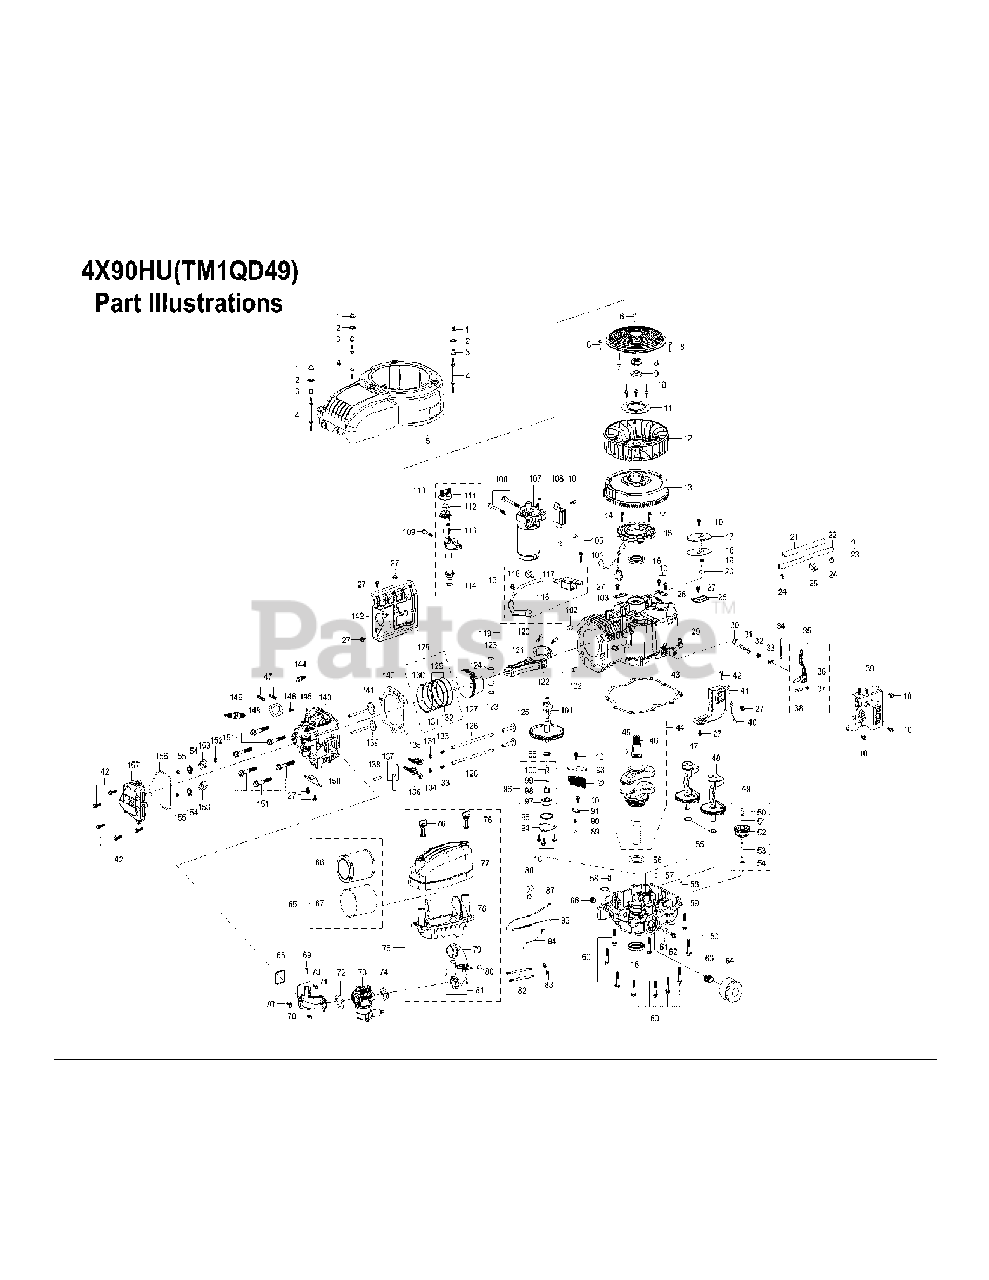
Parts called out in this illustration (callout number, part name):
1	NUT
2	WASHER
3	ENGINE SHROUD SPACER
4	STARTER / SHROUD STUD M6×113
5	SHROUD/AIR SHIELD
6	SCREW 5.5×25
7	DEBRIS SHIELD
8	NUT M20×1.5
9	WASHER 20.5×5×40
10	BOLT M6×14
11	VANE PLATE
12	COOLING FAN
13	FLYWHEEL
14	BOLT M5×25
15	CHARGING COIL
16	OIL SEAL 38×58×8
17	BREATHER COVER
18	GASKET, BREATHER COVER
19	BREATHER VALVE SPRING
20	SECOND AIR VAVLE
21	TUBING PROTECTIVE SIEEVE
22	FUEL HOSE 6.3×12.5×250
24	CLAMP, FUEL HOSE
25	WIRE CLAMP
26	WIRE PLATE II
27	BOLT M6×12
29	CRANKCASE
30	GOVERNOR GEAR SHAFT
31	WASHER 8×0.8×16
32	OIL SEAL 8×14×4
33	COTTER PIN
34	GOVERNOR SPRING
35	GOVERNOR LEVER
36	GOVERNOR ARM
37	GOVERNOR ARM NUT M6
38	GOVERNOR ARM BOLT
39	GOVERNOR GEAR BRACKET ASSY
40	GROUND CONNECTION
41	SHROUD/RIGHT
42	BOLT M6×25
43	GASKET, CRANKCASE COVER
44	CRANKSHAFT ASSEMBLY
45	WOODRUFF KEY
46	CRANKSHAFT
47	BALANCE SHAFT/L
48	BALANCE SHAFT/R
49	GOVERNOR GEAR ASSEMBLY
50	GOVERNOR SLIDE CAP
51	GOVERNOR SHAFT STOP RING
52	GOVERNOR GEAR
53	GOVERNOR SHAFT
54	GOVERNOR GEAR WASHER
55	WASHER 17.2×26×1
56	WASHER 38.3×54×1
57	DOWEL PIN 7×14
58	DOWEL PIN 9×14
59	CRANKCASE COVER
60	BOLT M8×45
61	WASHER 8.3×1.5×17
62	BOLT M8×15
63	FILTER CONNECTOR PIPE
64	OIL FILTER
65	AIR FILTER ELEMENT
66	PAPER FILTER
67	SPONGE FILTER
68	INTAKE PIPE RING
69	SCREW 4.2×20
70	BOLT M6×22
71	INTAKE PIPE
72	CARBURETOR GASKET
73	CARBURETOR
74	AIR FILTER GASKET
75	AIR FILTER ASSEMBLY
76	AIR FILTER COVER SCREW
77	AIR FILTER COVER
78	SILENCER PLATE
79	MANIFOLD
80	RUBBER CAP
81	SCREW 4.2×12
82	STUD M6×92
83	GOVERNOR ARM NUT M6
84	CHOKE LEVER
85	IDLE SPRING
86	DRAIN BOLT
87	THROTTLE LINKAGE
88	VENTING HOUSE
89	STEEL BALL 8.731
90	PRESSURE RELEASE VALVE SPRING
91	PRESSURE RELEASE VALVE COVER
92	FILTER SCREEN
93	FILTER COVER
94	OIL SEPARATER
95	GASKET, CYLINDER HEAD COVER
96	OIL PUMP ASSEMBLY
97	OIL PUMP OUTER SHAFT ROTATOR
98	OIL PUMP INNER SHAFT ROTATOR
99	OIL PUMP PIN
100	OIL PUMP SHAFT
101	CAMSHAFT
102	DOWEL PIN 12×16
103	WIRE PLATE I
104	BOLT M6×28
105	DOWEL PIN 10×12
106	REGULATOR
107	ELECTRIC STARTER
108	BOLT M8×80
109	BOLT M6×45
110	DIPSTICK ASSEMBLY
111	DIPSTICK COVER
112	UPPER O-RING
113	DIPSTICK SEAT
114	LOWER O-RING
115	IGNITION COIL ASSEMBLY
116	VIBRATION PAD
117	WIRE CLAMP
118	IGNITION COIL
119	CONNECTING ROD
120	CONNECTING ROD BOLT
121	CONNECTING ROD CAP
122	CONNECTING ROD
123	CIRCLIP, PISTON PIN
124	PISTON PIN
125	TAPPET
126	PUSH ROD
127	PISTON
128	PISTON RING SET
129	SCRAPER RING, OIL RING
130	1ST PISTON RING
131	2ND PISTON RING
132	LINING RING, OIL RING
133	VALVE CLEARANCE ADJUSTMENT SCREWS COMBINATION
135	ROCKER ARM
136	ROCKER ARM
137	ROCKER ARM CORE SHAFT
138	ROCKER ARM CORE SHAFT BOLT
139	EXHAUST VAVLE
140	GASKET, CYLINDER HEAD
141	INTAKE VAVLE
142	SHROUD/LIFT
143	CYLINDER HEAD
144	HOOK BOLT
145	WASHER 5.3×1×10
146	BOLT M5×10
148	GASKET, MUFFLER
149	SPARK PLUG(F6RTC)
150	SHROUD
151	BOLT M10×1.25×70
152	INTAKE VALVE SEAL
153	VALVE SPRING
154	VALVE SPRING SEAT
155	VALVE COLLET
156	VALVE COVER RING
157	CYLINDER HEAD COVER
